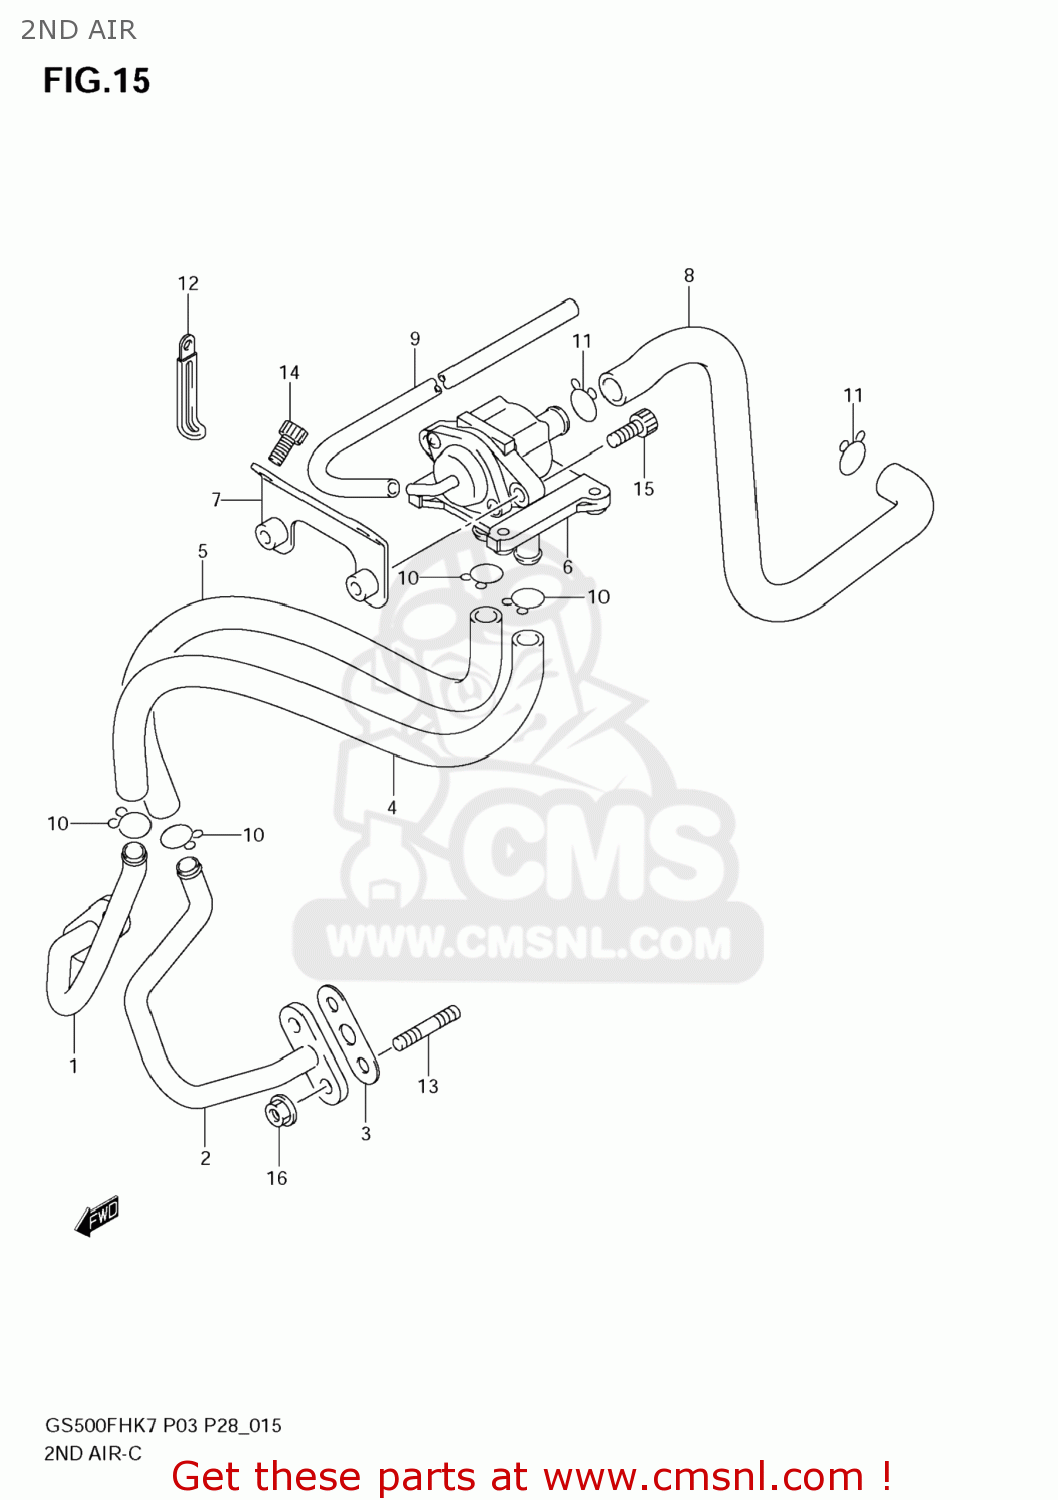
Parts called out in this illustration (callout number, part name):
1	PIPE,2ND AIR,R
2	PIPE,2ND AIR,L
3	GASKET,2ND AIR (NAS)
4	HOSE , 2ND AIR REED VALVE RH
5	HOSE , 2ND AIR REED VALVE LH
6	VALVE ASSY,2ND AIR
7	BRACKET,2ND AI
8	HOSE, 2ND AIRC
9	HOSE(4X7X600)
10	CLIP
11	CLIP
12	CLAMP(L:45)
13	BOLT,STUD
14	BOLT
15	BOLT 6X16
16	NUT
